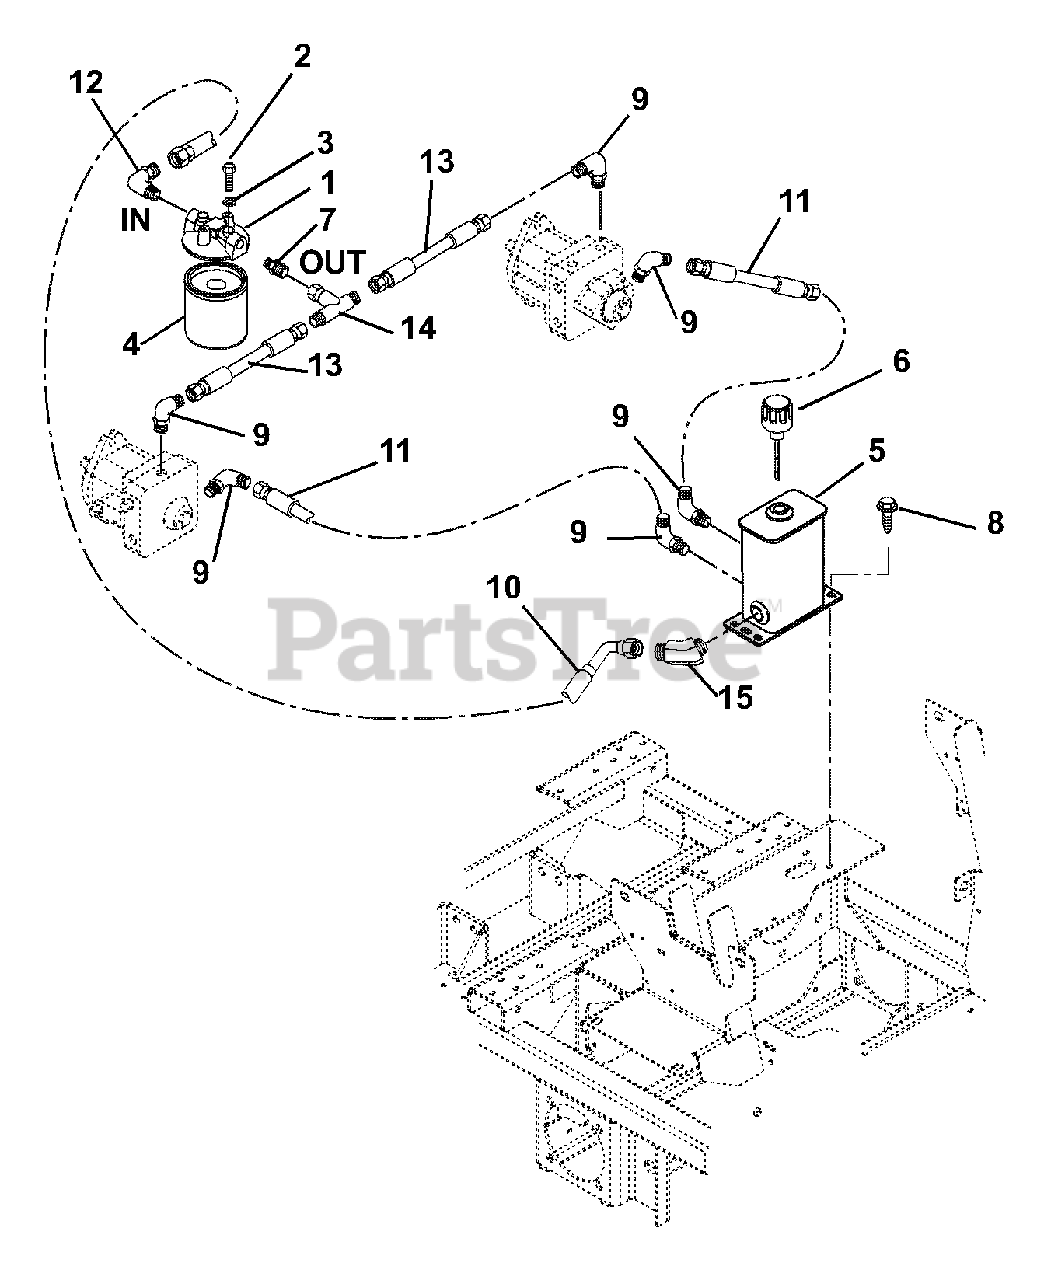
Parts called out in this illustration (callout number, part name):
1	Filter Housing
2	Bolt-Hex .25-20 x .50 Grade 5
3	Washer-Locking .25 x .062
4	Filter Element
5	Body, Hydraulic Tank
6	Breather, Dipstick
7	Fitting, Hydraulic, Straight Steel
8	Screw-Tapping .38-16 x .75 Hex Washer Head
9	Fitting, Hydraulic, 90 Degree Elbow
10	Hose-Hydraulic Valve to Tank
11	Hose, Hydraulic, 10-inch
12	Fitting, Hydraulic, 90 Degree Elbow
13	Hose, Hydraulic .50, 5-Inch
14	Fitting, Hydraulic Tee
15	Fitting, Hydraulic .45 Degree Elbow
